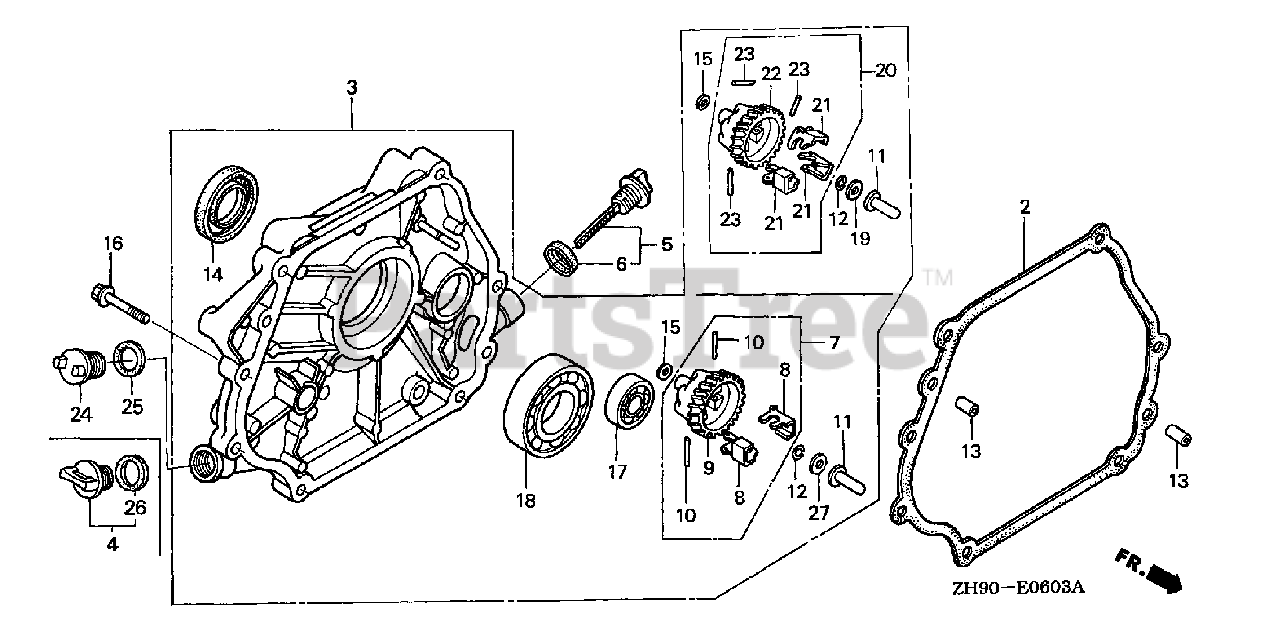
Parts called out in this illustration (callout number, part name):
2	GASKET, CASE COVER
3	COVER ASSY., CRANKCASE (Q-TYPE)(BALANCER)
3	COVER ASSY., CRANKCASE
4	CAP ASSY., OIL FILLER
5	CAP ASSY., OIL FILLER
6	GASKET, OIL FILLER CAP
7	GOVERNOR ASSY. (BALANCER)
8	WEIGHT, GOVERNOR
9	HOLDER, GOVERNOR WEIGHT
10	PIN, GOVERNOR WEIGHT
11	SLIDER, GOVERNOR
12	CLIP, GOVERNOR HOLDER
13	PIN, DOWEL (8X12)
14	OIL SEAL (30X46X8)
15	WASHER, PLAIN (6MM)
16	BOLT, FLANGE (8X35)
17	BEARING, RADIAL BALL (6202)
18	BEARING, RADIAL BALL (6206)
19	WASHER (6X16)
20	GOVERNOR ASSY.
21	WEIGHT, GOVERNOR
22	HOLDER, GOVERNOR WEIGHT
23	PIN, GOVERNOR WEIGHT
26	GASKET, OIL FILLER CAP
